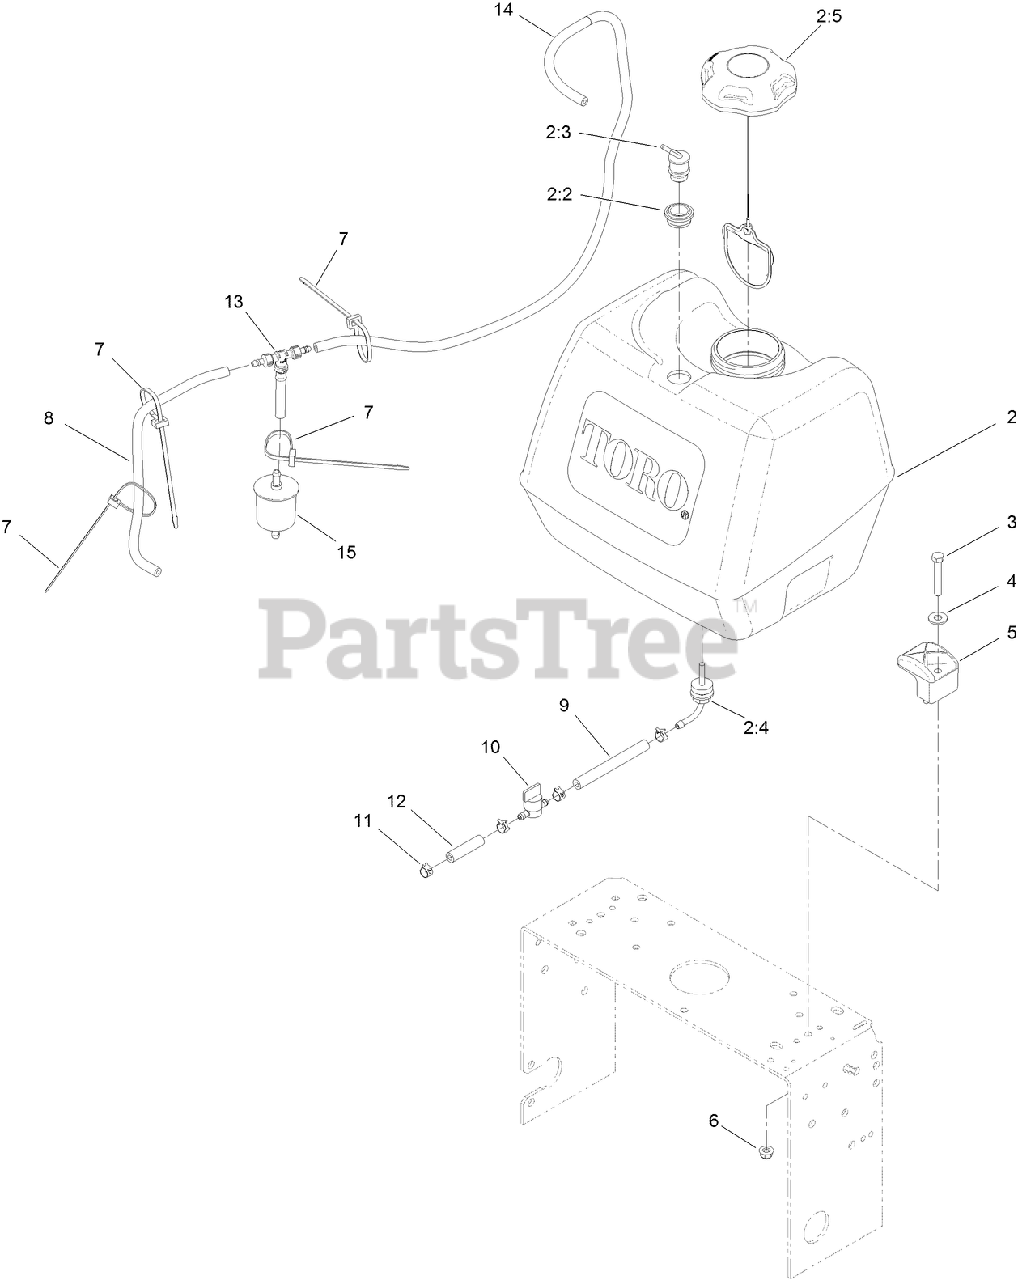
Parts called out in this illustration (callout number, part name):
2	FUEL TANK ASM
2:2	GROMMET
2:3	VALVE-VENT, FUEL
2:4	FITTING-FUEL, BULKHEAD
2:5	CAP-FUEL, RATCHETING
3	SCREW-HH
4	WASHER-FLAT
6	NUT-HF, NI
7	TIE-CABLE
8	HOSE-FUEL
9	HOSE-FUEL
10	VALVE-FUEL
11	CLAMP-HOSE
12	HOSE-FUEL
13	TEE AND CHECK
14	HOSE-EMISSIONS
15	FILTER-FUEL
